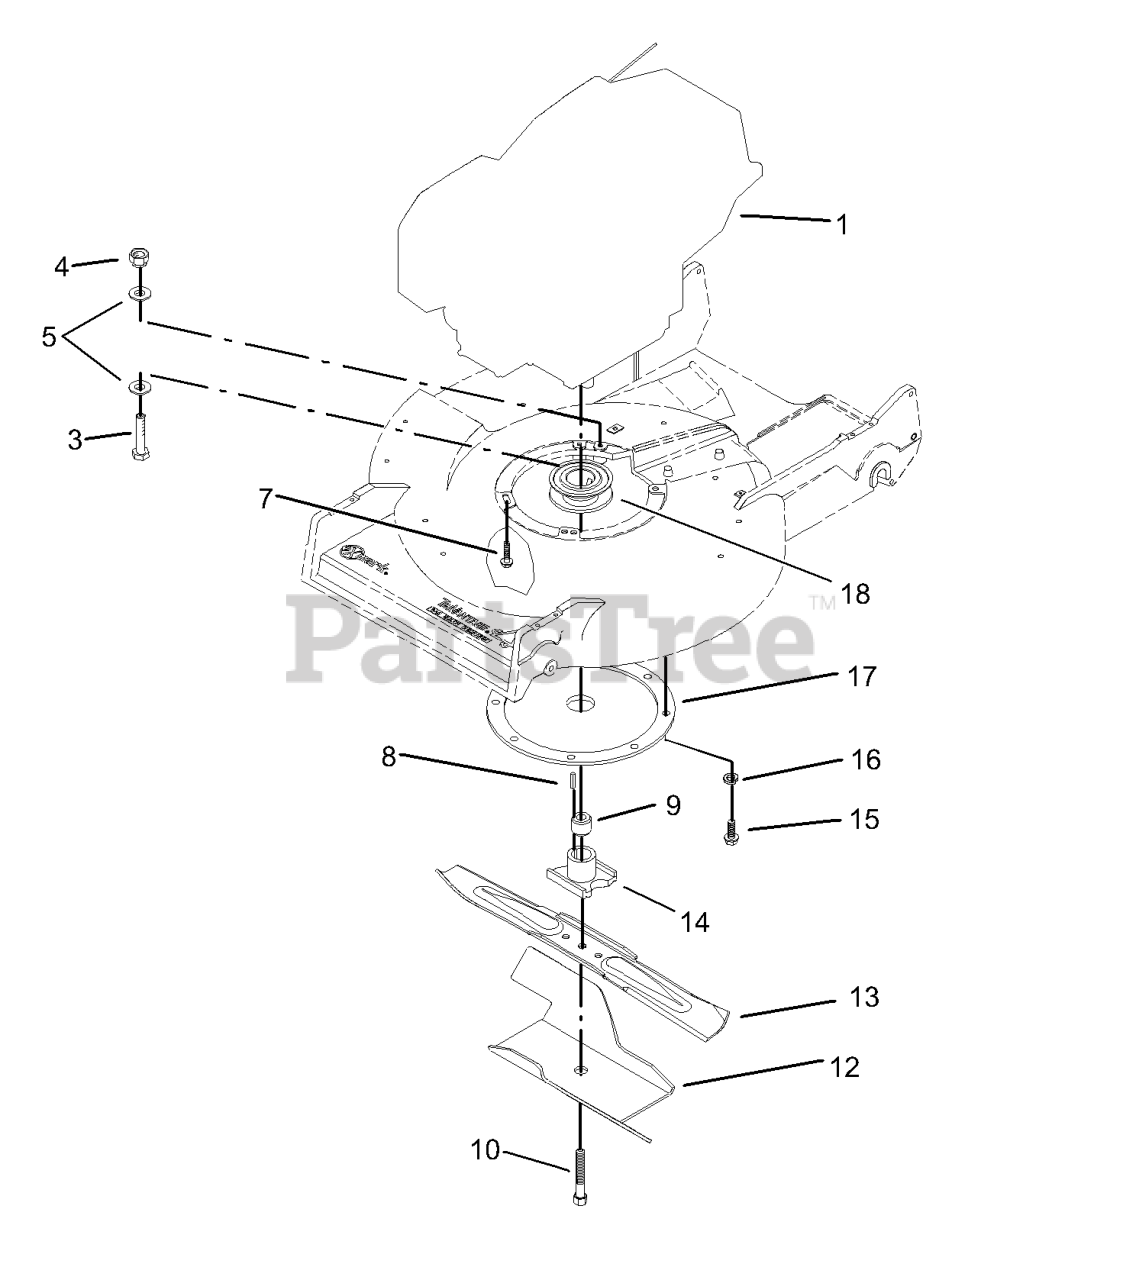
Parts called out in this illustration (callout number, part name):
3	Screw-Hh
4	NUT-LOCK, NI
5	WASHER-PLAIN
7	SCREW-SHOULDER
8	KEY-SQUARE
9	SPACER-RETAINER, BLADE
12	STIFFENER-BLADE
14	RETAINER-BLADE
15	Screw-HWH 5/16-18 X 3/4 Tf
16	WASHER-LOCK, INTERNAL
18	PULLEY-DRIVER
